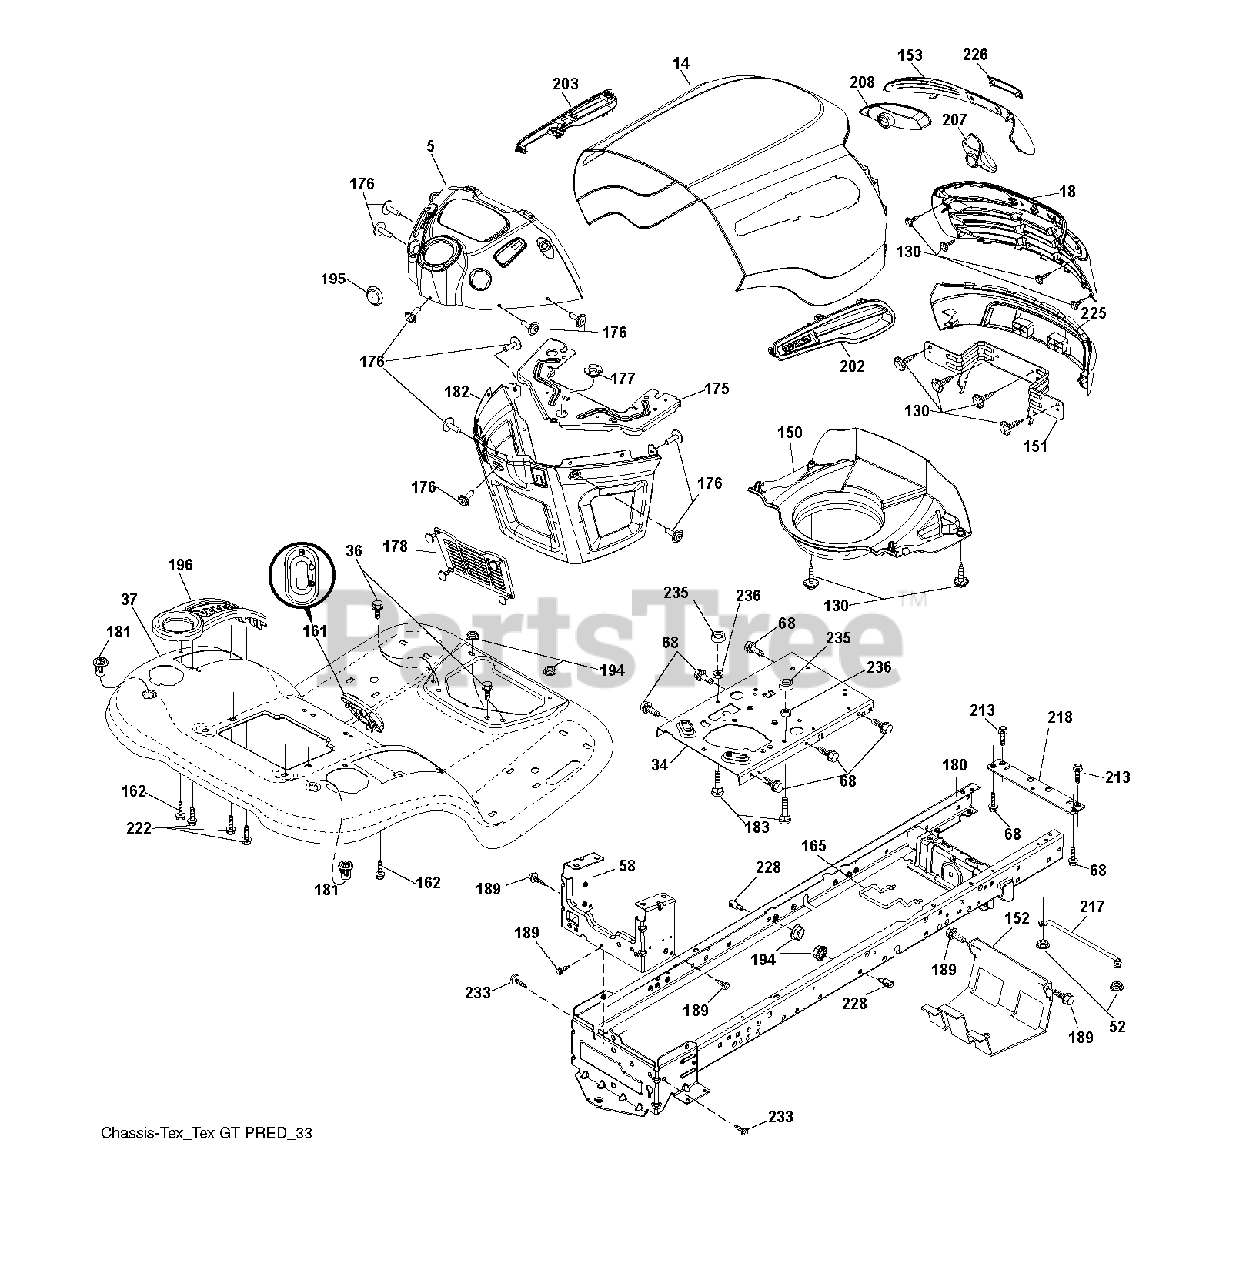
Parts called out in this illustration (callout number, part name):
34	PLATE.ENGINE.WELDED.CHASSIS
36	SCREW 5/16"
52	LOCKNUT
58	DRAWBAR.UPPER.2PC,LRG.FENDER
130	SCREW.#10 X 0.750.BOS THREAD
152	SHIELD BROWNING
161	CONSOLE.FUEL.WINDOW.STGT.BLACK
162	SCREW.HI-LO.CONSOLE
165	SUPPORT.TANK.REAR.W/TE
175	PLATE.CROSSMEMBER.HUSQ
176	SCREW.#10-24X5/8.RN.QU
177	BUSHING,STEERING
178	CARGO.ASM.NET.TXGT.W/C
180	CHASS.WLDMNT.TL.12GA/2P.48/54
181	FEND/FTRST.PCH.CPH.NFW
182	DASH.LOWER.COMMON.12V.ADAPTOR
183	BOLT.5/16-18X1-1/4 FULL.THREAD
189	SCREW
194	NUT LOCK HEX FLANGE 5/16-18
195	PLUG.HOLE.DASH.LOWER.12V.BLK
217	ROD.PIVOT.HOOD
218	X-PIECE.HOOD.STOP.NON/
222	SCREW.1/4-20X5/8
228	STUD.FASTNER.W/ANTI-ROTATE
233	BOLT.SHOULDER
235	SPACER FENDER
236	NUT.CENTERLOCK.5/16-
